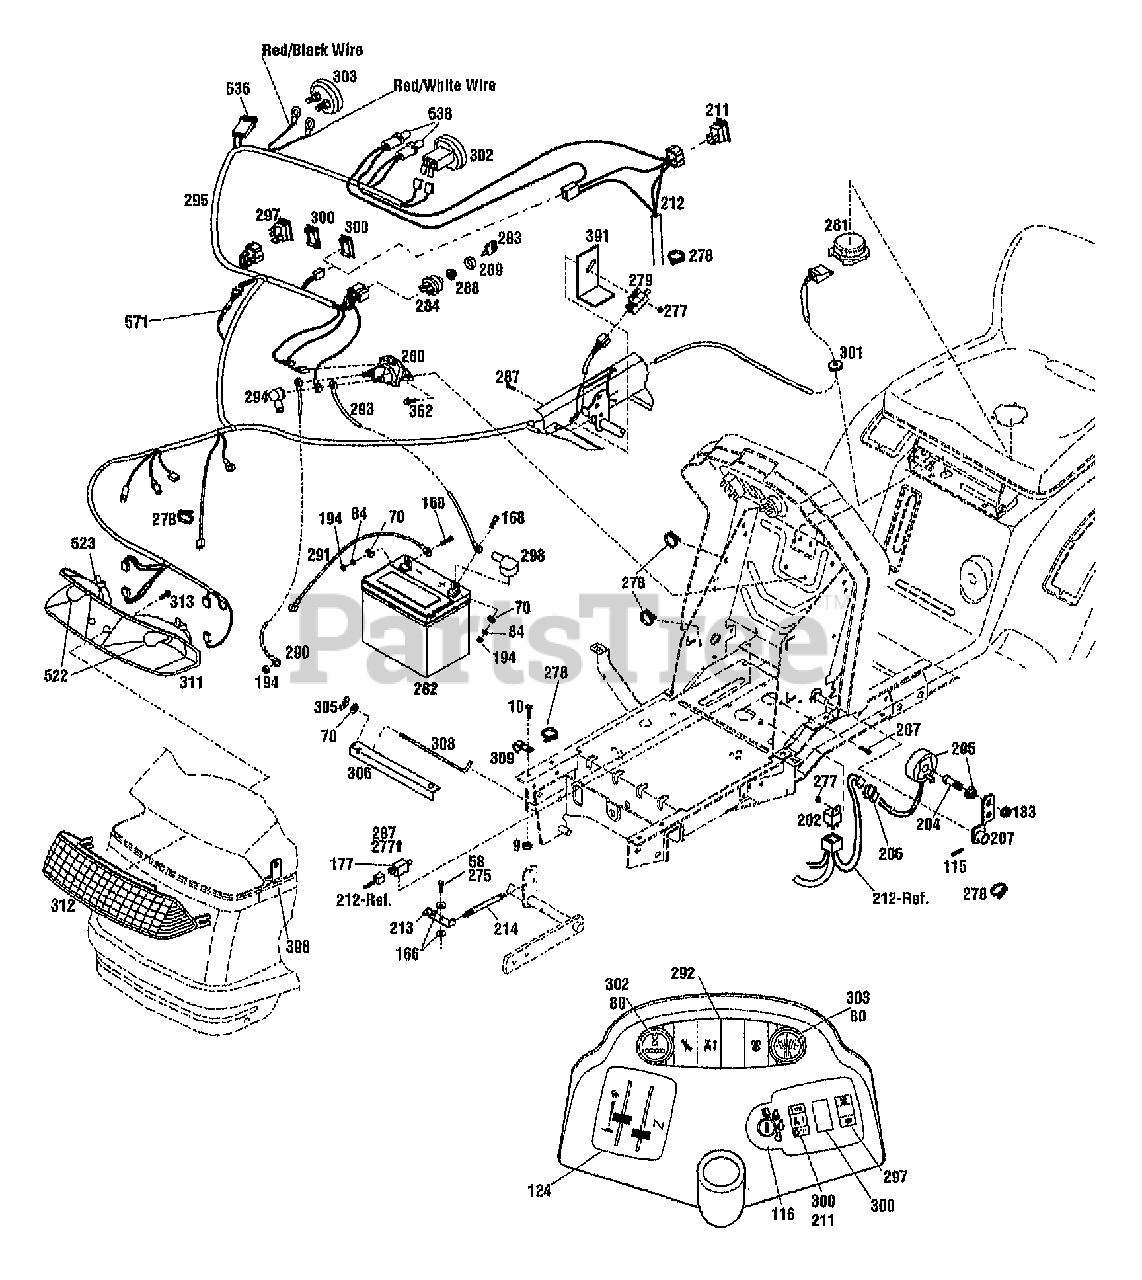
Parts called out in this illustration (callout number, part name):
10	SCR-HHC 5/16-18X.75 GR 5 ZP
58	NUT-HT LK 1/4-20 {13105}
70	WASHER-FLAT 1/4 SAE
80	CAP {13103,13104}
84	WASHER-LK .25 ZP
115	PIN-ROLL .188X1.0 {13105}
116	DECAL-IGNITION
124	DECAL-CONTROL {13103}
124	DECAL-CONTROL {13104,13105}
133	NUT-WHIZ LOCK {13105}
166	WASHER-FLAT 1.25X.28X.062 ZP {13105}
168	SCR-HH 1/4-20X.75 G5 ZP
177	SWITCH {13105}
194	NUT-HEX 1/4-20 ZP
202	RELAY-SPEED CONTROL {13105}
204	SCR-SPECIAL {13105}
205	ASSM-MAGNET {13105}
206	PIN-TERM HOUSING {13105}
207	ARM-CRUISE {13105}
211	SWITCH-CRUISE {13105}
212	HARNESS-CRUISE {13105}
213	ARM-CRUISE {13105}
214	SPRING {13105}
275	SCR-HH 1/4-20X.625 G5 ZP
277	NUT W/LKWASHER 10-24 ZP
278	TIE-CABLE NYLON BLACK
279	SWITCH
280	SOLENOID
281	SWITCH-SEAT
282	BATTERY
283	KEY-IGNITION
287	SCR-HHS 10-24X.625 ZP
288	NUT-SWITCH
289	CAP-SWITCH
290	CABLE-STARTER
291	CABLE-BATTERY (-)
293	CABLE-BATTERY
294	BOOT-SOLENOID
295	HARNESS-MAIN {13103,13104}
295	HARNESS-MAIN {13105}
297	SWITCH-PTO
298	BOOT-TERMINAL
300	COVER-SWITCH {13103,13104}
301	GROMMET
302	METER-HOUR {13105}
303	AMMETER {13105}
305	NUT-WING
306	CLAMP-BATTERY
308	SCR-HOOK
309	CLIP-J
311	ASSM-HEADLIGHT
312	LENSE-HEADLIGHT
362	SCR 1/4-20X.5 FL SELF TAP
391	BRACKET-SWITCH
398	CLIP-RETAINING
522	LIGHTBULB
523	SOCKET
536	FUSE
538	LIGHTBULB
571	ASSM-DIODE
